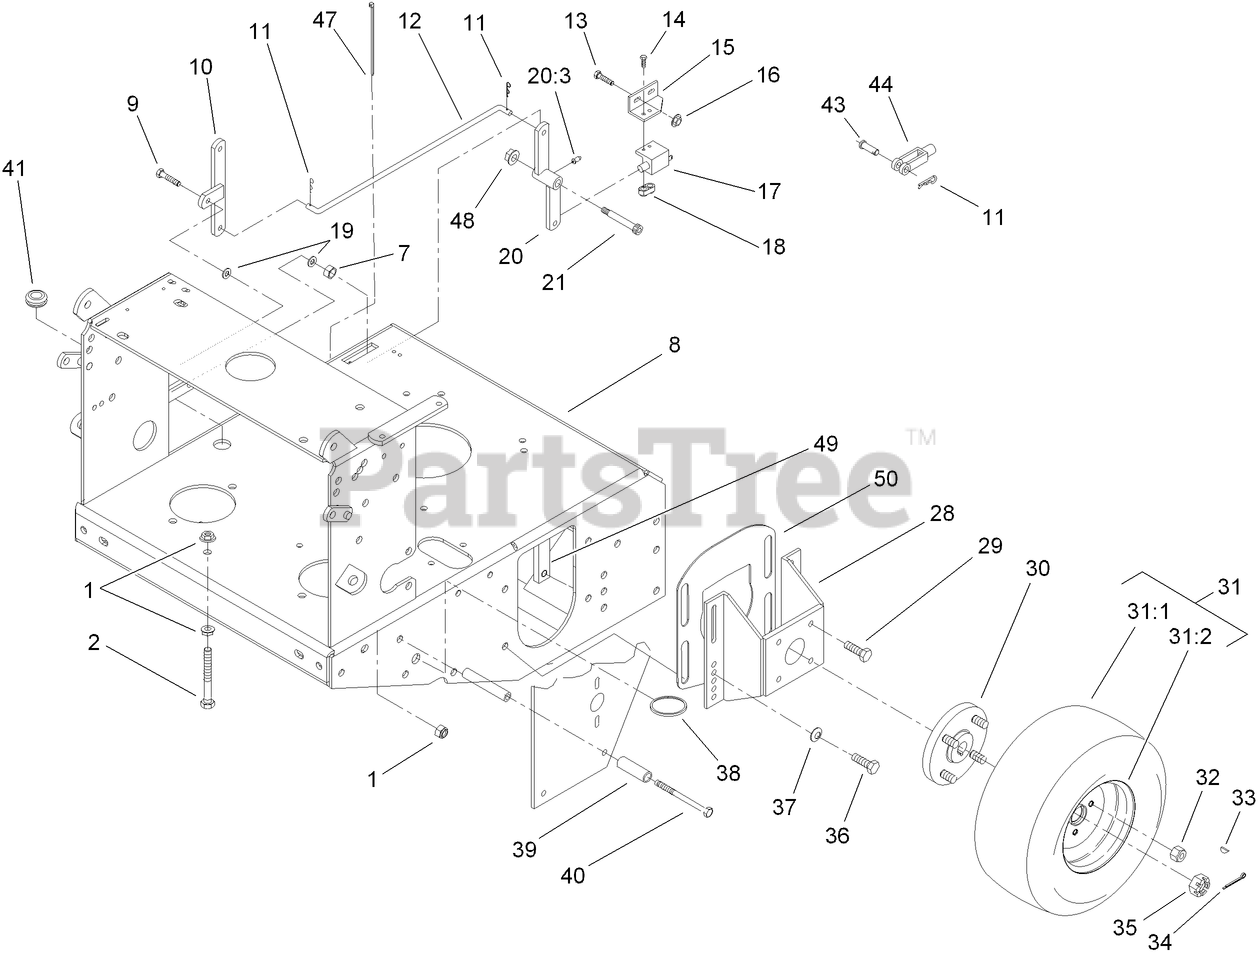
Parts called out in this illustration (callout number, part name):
1	NUT-HHF, WHIZ
2	SCREW-HH
7	NUT-LOCK, NI
8	HYDRO FRAME ASM
9	SCREW-HH
10	BELLCRANK ASM
11	PIN-COTTER
12	Linkage-Engage, Blade
13	SCREW-HH
14	SCREW-PPH
15	Bracket-Switch, Blade
16	NUT-HF
17	SWITCH-OPEN, NORMALLY
18	PLATE-TAPPED
19	WASHER-PLAIN
20	Bellcrank ASM
20:3	FITTING-GREASE, 90 DEG
28	Mount-Motor
29	SCREW-HHF
30	WHEEL HUB ASM
31	Wheel And Tire ASM
31:1	Tire-Turfmaster
31:2	Wheel-Rim
32	NUT-LUG
33	Key-Woodruff
34	PIN-COTTER
35	NUT-HEX, SLOTTED
36	SCREW-HH
37	WASHER-BELLEVILLE
38	Ring-Split
39	SPACER-SHORT
40	SCREW-HH
41	GROMMET
43	PIN-CLEVIS
44	YOKE-ADJUSTABLE
47	TIE-CABLE
48	NUT-HF
49	BAR-NUT
50	GUARD-DEBRIS
